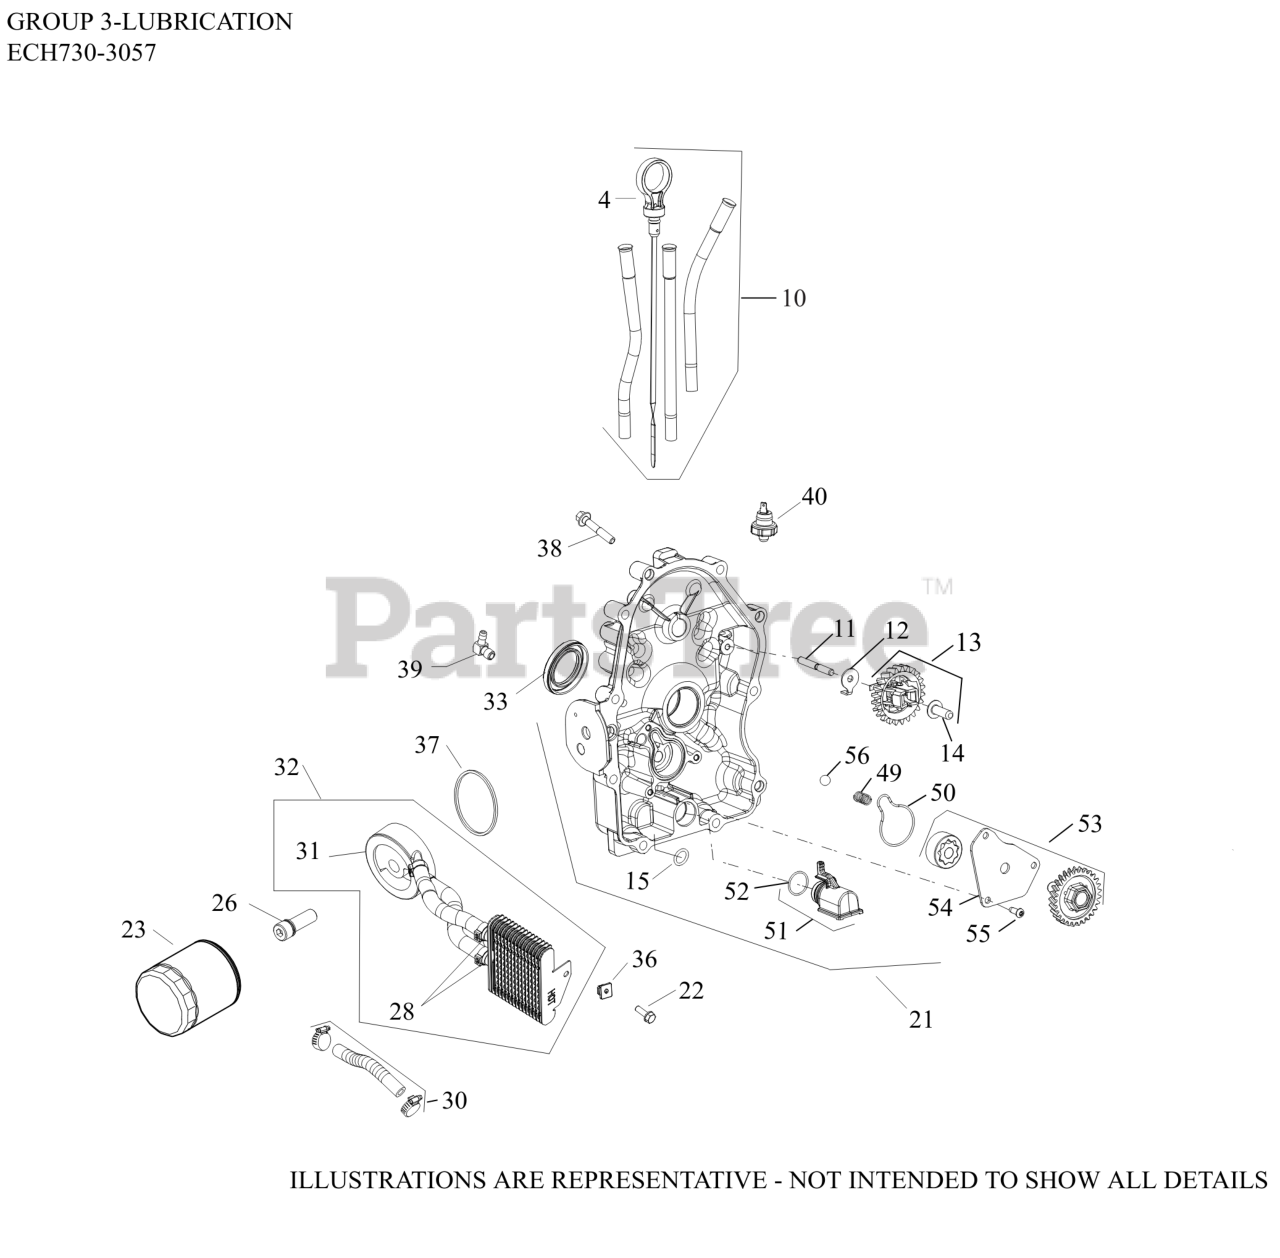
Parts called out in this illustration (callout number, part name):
10	KIT, DIPSTICK/DIPSTICK TUBES
11	SHAFT, GOVERNOR GEAR
12	TAB, LOCKING
13	KIT, GOVERNOR GEAR W/PIN
14	PIN, GOVERNOR REGULATING
21	KIT, CLOSURE PLATE ASSY
22	SCREW, TAP M6X1.7X18
23	OIL FILTER
26	NIPPLE, OIL FILTER - (#2413608S)
28	CLAMP, HOSE LOW PROFILE
30	KIT, HOSE 140MM
31	ADAPTER, OIL FILTER (CH EFI)
32	COOLER,OIL&DIVERTER ASSY-USE 24 594 67-S
32	COOLER, OIL & DIVERTER ASSEMBLY
36	NUT, PLASTIC - BLACK
37	O-RING, OIL COOLER
38	SCREW, FLG M8X1.25X45
38	SCREW, HEX FLANGE
39	CONNECTOR, 90 DEG. HOSE
40	SENSOR, OIL PSI
49	SPRING, COMPRESSION
50	SEAL, OIL PUMP COVER
51	PICK-UP ASSEMBLY, OIL
52	O-RING, OIL PICK-UP
53	PUMP ASSEMBLY, OIL
54	COVER, OIL PUMP
55	SCREW, BUTTON HEAD
56	PRESSURE RELIEF BALL
